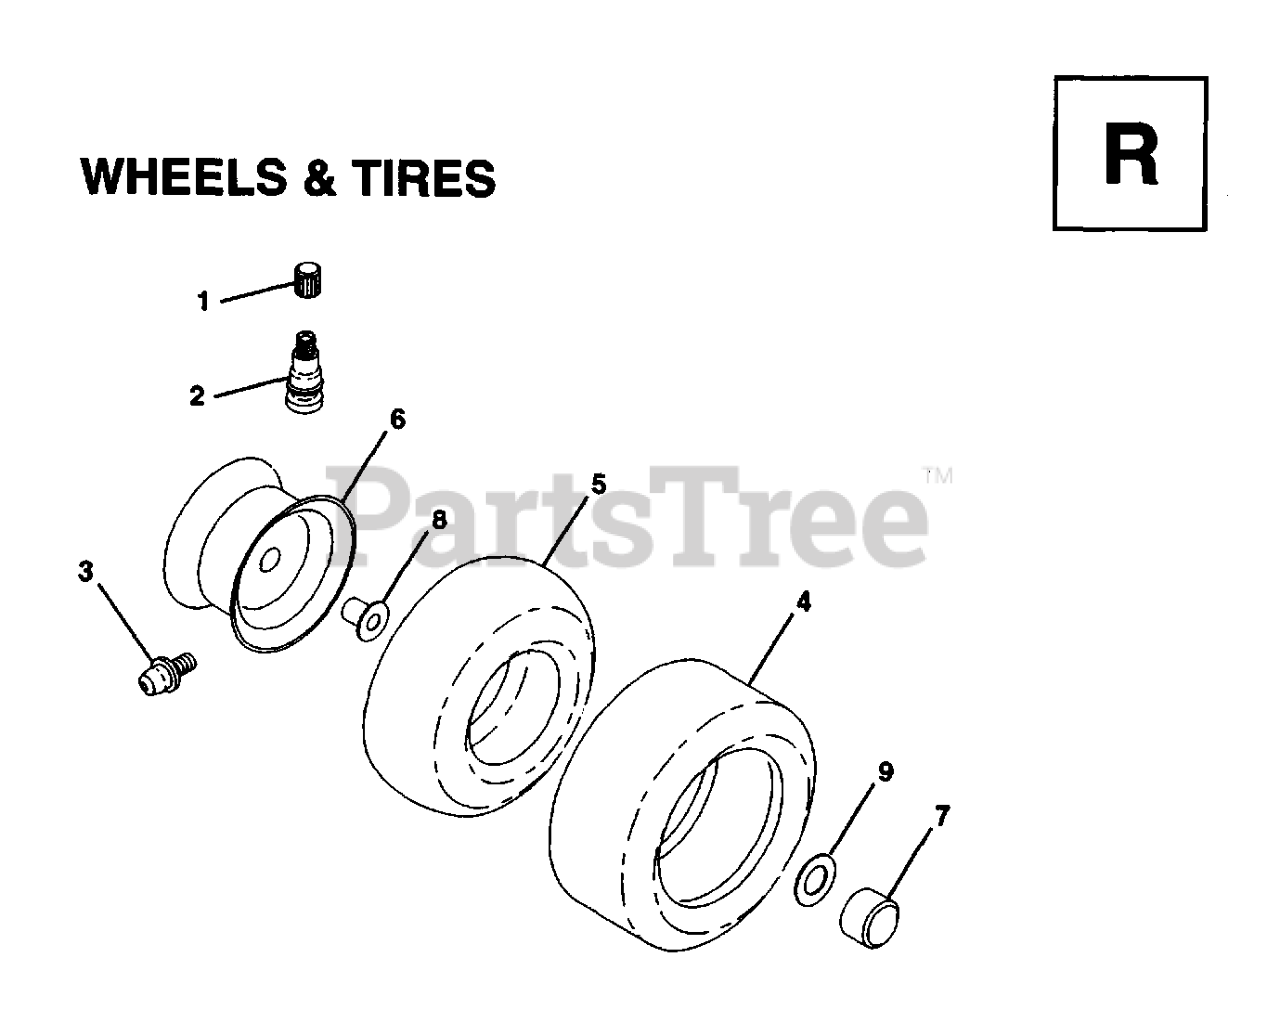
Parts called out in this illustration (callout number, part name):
2	VALVE STEM LT
3	FITTING LT
4	TIRE.13X5-6.TURF.SAVER.FRONT
5	TUBE.16X6.5/7.5-8
5	TUBE.5.3/4.5/6
6	RIM ASM REAR 8"
6	RIM-FRONT
7	COVER.FRONT.WHEEL
7	CAP.HUB.FRONT.LT.BLACK
7	CAP,HUB REAR
8	BEARING T
